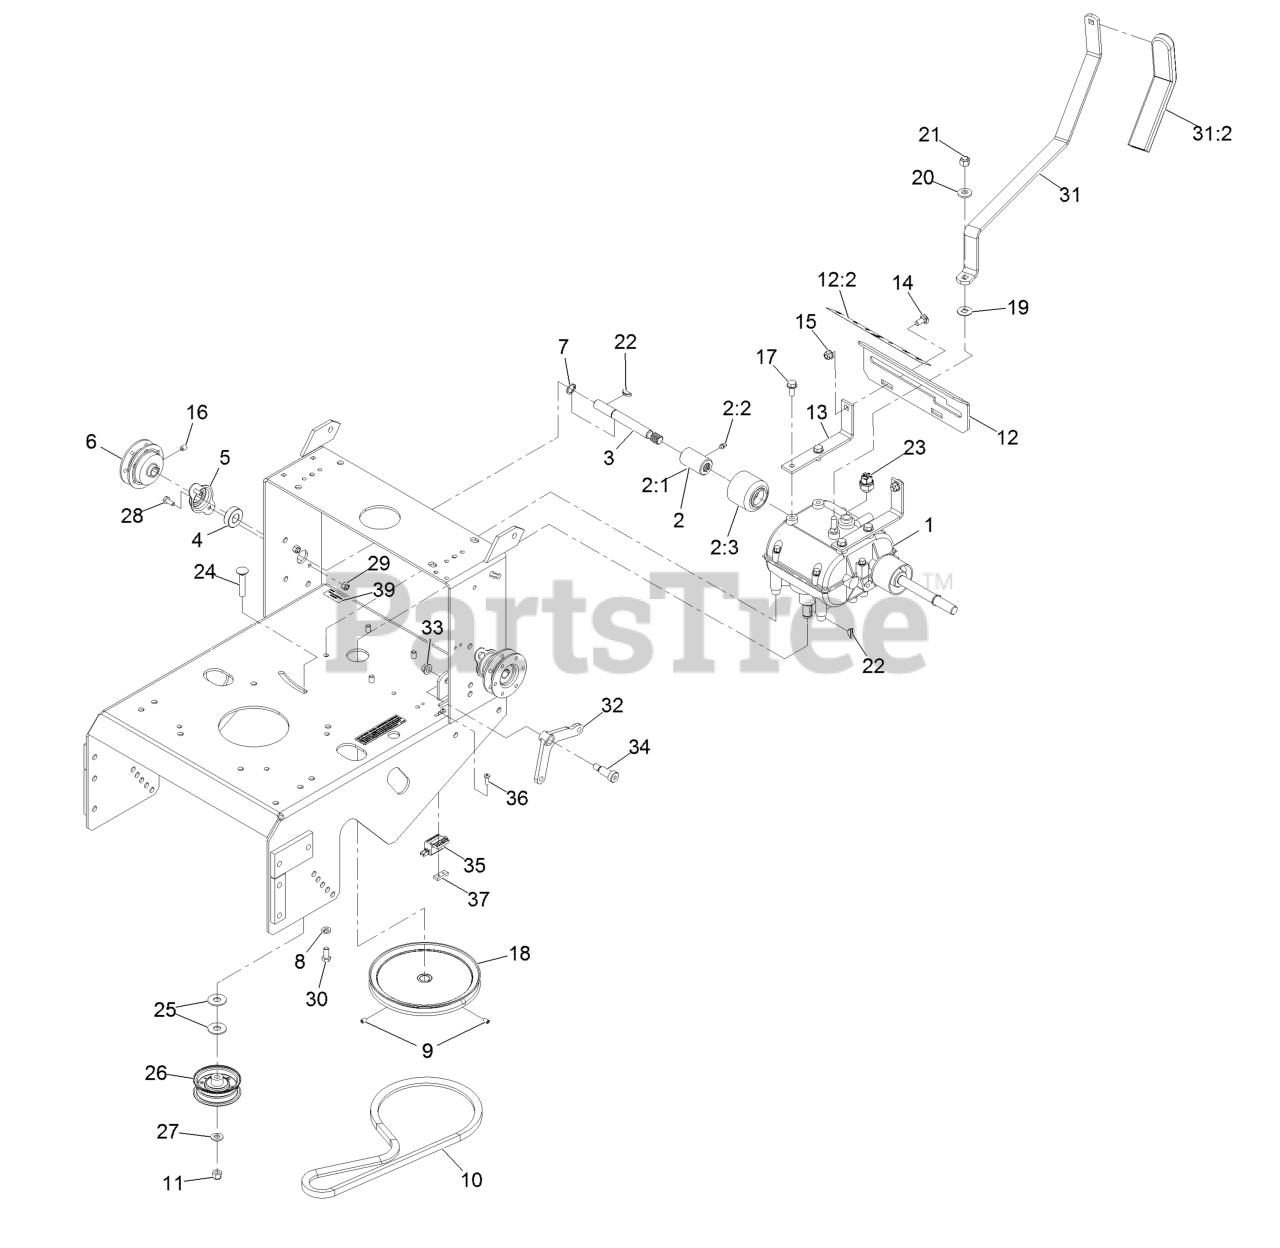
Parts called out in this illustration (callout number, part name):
1	Transmission-5 Speed
2	Coupling, W/Guard And Zerk
2:1	Coupler
2:2	Zerk-1/4-28 Str
2:3	Guard-Coupler
3	Shaft-Transmission
4	Bearing-Shaft
5	Flange-Output
6	Sheave-Transmission
7	Ring-Retaining
8	Washer-Lock 5/16 Heavy
9	Setscrew-1/4-20 X 3/8
10	Belt, Transmission Drive
11	Nut-Nyloc 3/8-16
12	Asm, Shifter Plate W/ Decals
12:2	Decal-Speed, Ground
13	Bracket-Plate, Shift
14	Bolt-Carriage 5/16-18 X 3/4
15	Nut-Nyloc 5/16-18 Flg
16	Setscrew-5/16-18 X 3/8
17	Screw-HWH 5/16-18 X 3/4 Tf
18	Sheave-Transmission
20	Washer-Spring Disc 3/8
21	Nut-Nyloc 3/8-24
22	Key-Woodruff #9 3/4 X 3/16
23	Switch-Start, Neutral
24	Bolt-Carriage 3/8-16 X 2
25	Washer-7/16 Std
26	Pulley-Idler, Flat
27	Washer-3/8 SAE
28	Screw-HH 1/4-20 X 5/8
29	Nut-Nyloc 1/4-20
30	Screw-HH 5/16-18 X 3/4
31	Lever, Shift W/Grip
31:2	Grip Foam
32	Bellcrank
33	Nut-Whizlock 3/8-16
34	Bolt-Shoulder
35	Switch-N.O.
36	Screw-PPH #10-24 X 5/8
37	Plate-Tapped
39	Decal-Patent
